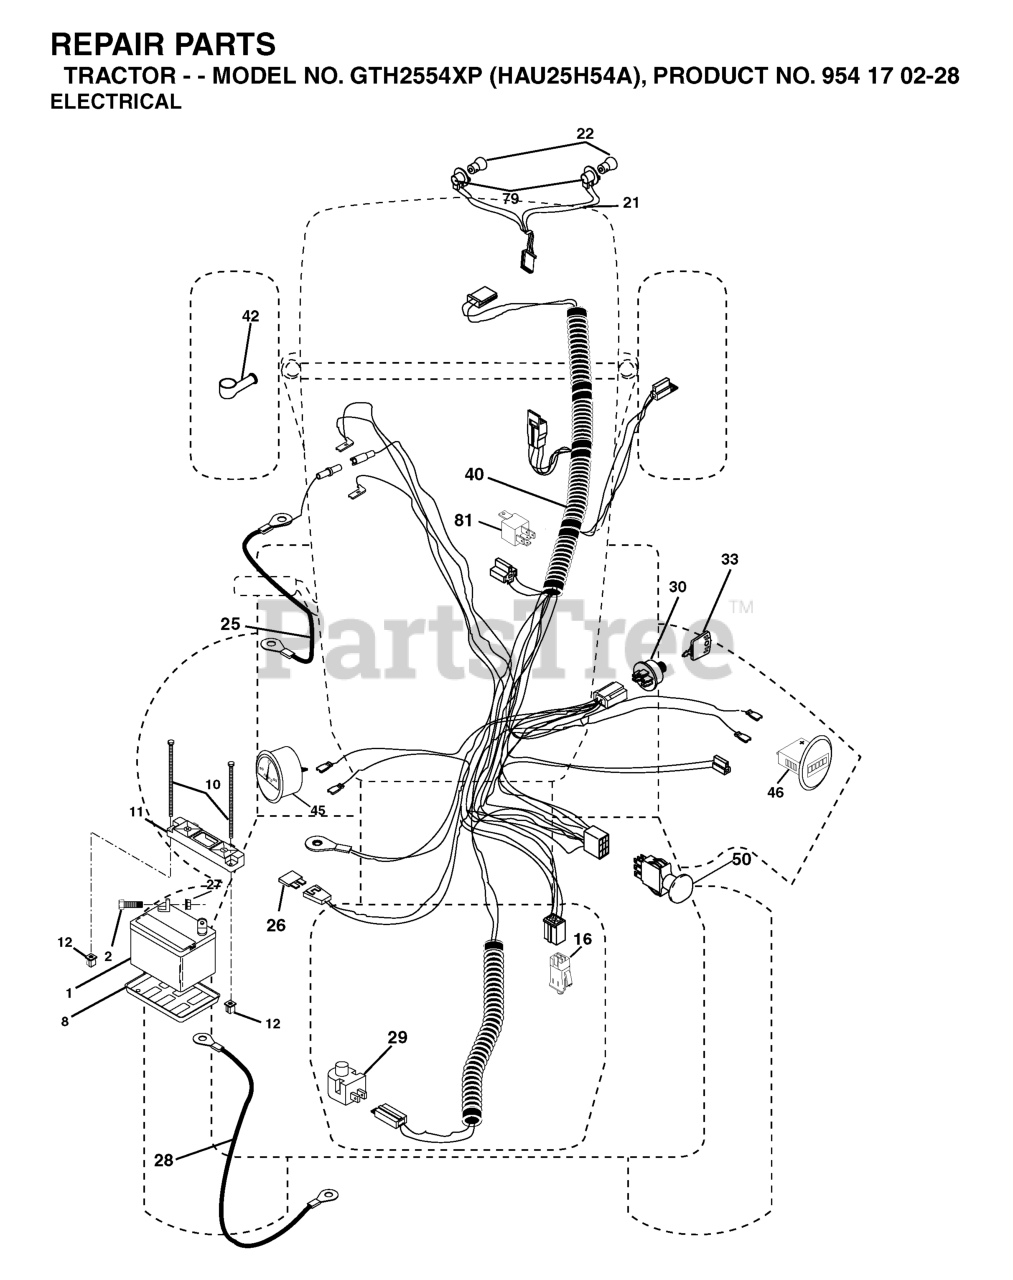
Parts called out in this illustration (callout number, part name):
1	BATTERY 12V .35 AMP
2	BOLT.HEX.1/4.X.3/4.DICHROMATE
8	BATTERY TRAY T
10	BOLT 1/4-20 X 7.5
11	BATTERY HOLDDOWN FRONT MOUNT
12	NUT, PUSH NYLON 1/4" BATTERY
16	SWITCH INTERLOOK PUSH-IN
21	HARNESS.W/LIGHT SOCKET
25	CABLE.4GA.RED.W/16GA.RED.WIRE
27	NUT
28	CABLE, GROUND
29	RP.SWITCH.PLUNGER.NC.GRAY
30	IGNITION SWITCH
33	KEY MLD GEN DELTA
40	HARNESS.IGNITION.VGT.NO.RELAY
42	COVER.TERMINAL.RED
45	RP AMMETER.ROUND.SILVER.DELTA
46	RP HOURMETER SNAP-IN
50	RP.PTO.SWITCH.8 TERMINAL.BLACK
79	BULB HOLDER ASM.
81	RELAY.ASSY.T
